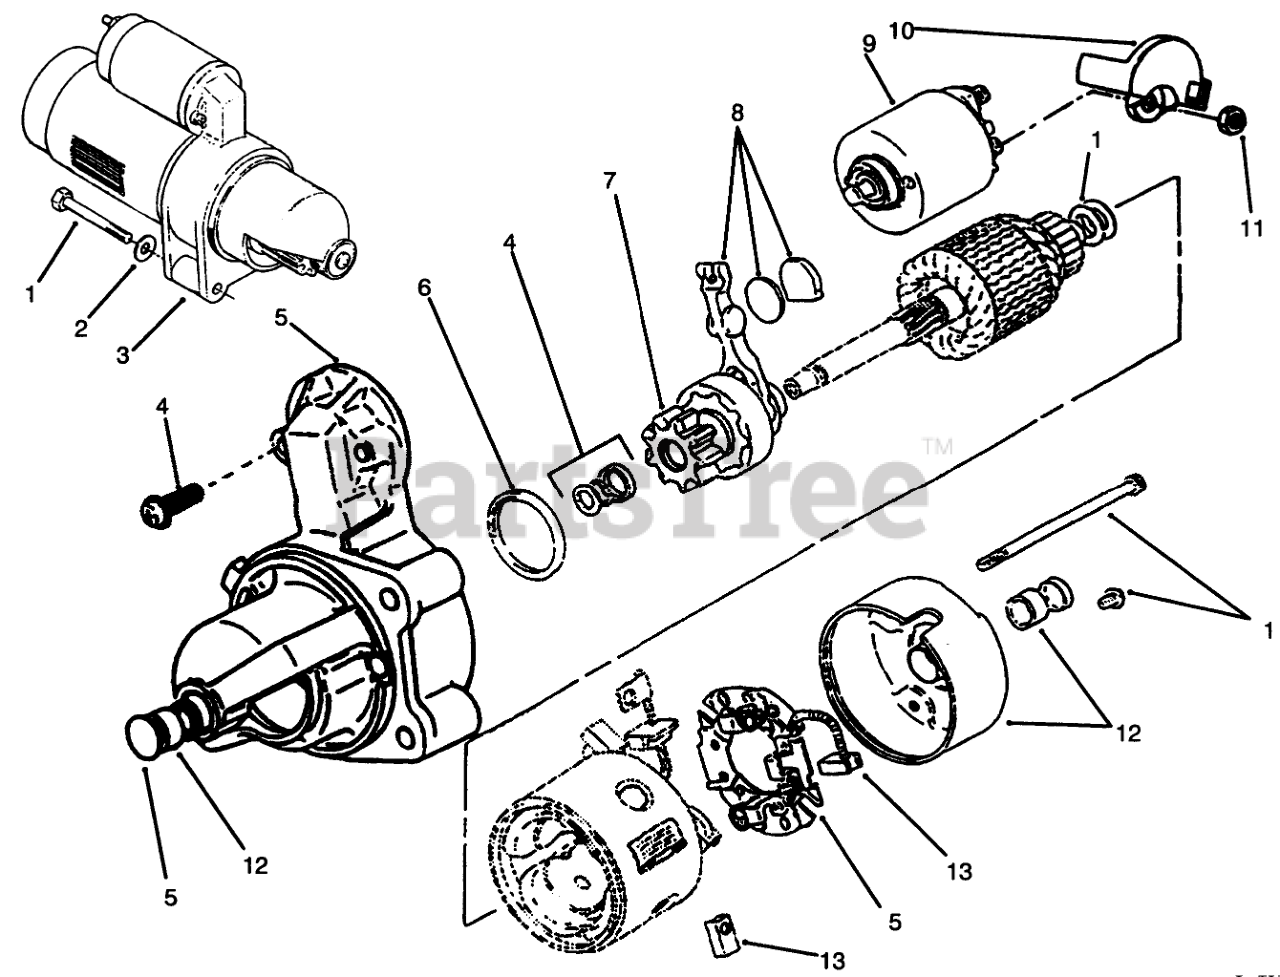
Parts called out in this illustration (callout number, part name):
1	SCREW
2	WASHER
3	STARTER
4	Kit-Hardware, Starter (Incl. (2) Solenoid Mtg Screws, 2 Thru Bolts, Armature Shims, Pinion Collar, & Retaining Ring)
5	Kit-Mounting Bracket (Incl. Ref. #13)
6	DUST-SEAL KIT
7	Assembly-Clutch, Starter (Incl. Pinion Gear)
8	Kit-Shift Lever, Starter (Incl. Lever, Wear Plate & Rubber Plug)
9	Kit-Solenoid, Starter (Incl. Solenoid & Spring Plunger)
10	Cap-Starter Solenoid
11	O-RING
12	Kit-Bushing, Starter (Incl. Rear Cap with Bushing & Front Bushing)
13	Kit-Brush, Starter (Incl. (2) Negative & (1) Positive Brushes)
